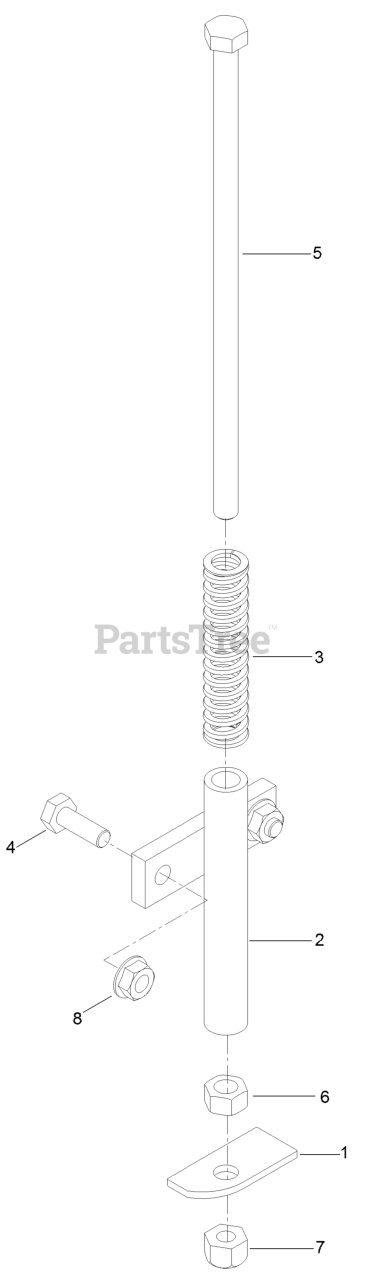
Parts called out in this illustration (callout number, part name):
1	Plate-Switch
2	MOUNT-SPRING, SEAT
3	SPRING-SWITCH, SEAT
4	SCREW-HH
5	SCREW-HH
6	NUT-HEX
7	NUT-LOCK, NI
